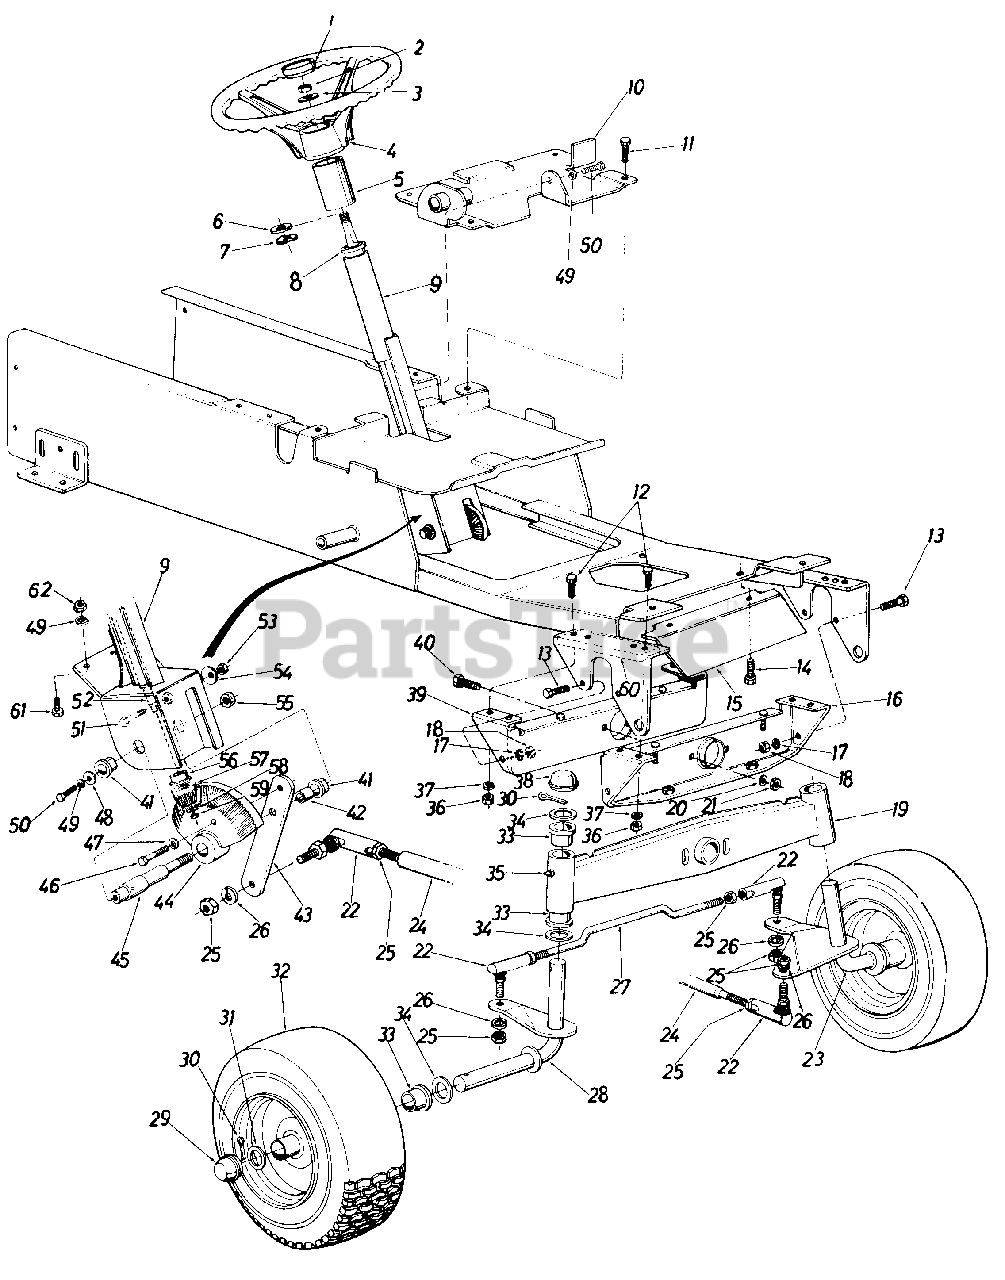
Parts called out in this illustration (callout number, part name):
1	Steering Wheel Cap
2	Hex Cent. L-Nut 5/16-18 Thd.
3	Bell-Wash.
4	Steering Wheel
5	Steering Tube-Outer
6	Double "D" Fl-Wash.
7	Wave Wash. .660 I.D. x .88 O.D.
8	Ball Brg. .63 I.D. x 1.38 O.D.
10	Dash Panel Base Plate Ass'y.
11	Hex Self-Tap Scr. 3/8-16 x .75" Lg.
12	Hex Scr. 3/8-16 x 1.50" Lg.
13	Hex Scr. 3/8-16 x 1.00" Lg.
14	Hex Wash. S.F. Tap Scr. 3/8-16 x 1.25" Lg.
15	Dust Shield
18	Hex Nut 3/8-16 Thd.
19	Pivot Bar Ass'y.
20	Bell-Wash. 3/8" Scr.
21	Hex Cent. L-Nut 3/8-16 Thd.
22	Drag Link End
23	Axle Ass'y.-L.H.
24	Drag Link
25	Hex Nut 1/2-20 Thd.
26	L-Wash. 1/2" Scr.
27	Tie Rod
28	Axle Ass'y.-R.H.
29	Dust Cover
30	Cotter Pin 3/16" Dia. x 1.50" Lg. *
31	Fl-Wash. 1.00" I.D. x 1.62"O.D.
33	Flange Brg. 1.00" I.D.
34	Fl-Wash. 1.00" I.D. x 1.62" O.D.
35	Grease Fitting
36	Hex Nut 3/8-16 Thd.
37	L-Wash. 3/8" Scr.
38	Dust Cover
40	Hex Scr. 3/8-16 x 2.50" Lg.
41	Flange Brg. w/Flats .753 I.D.
42	Steering Gear Shaft Spacer
43	Steering Arm
44	Bevel Gear
45	Steering Gear Shaft
46	Hex Scr. 3/8-16 x 1.50" Lg.
47	L-Wash. 3/8" Scr.
48	Fl-Wash. .406 I.D. x 1.25" O.D.
49	L-Wash. 3/8" Scr.*
50	Hex Scr. 3/8-16 x .75" Lg.
51	Nylon Hex Scr. 3/8-16 x 1.25" Lg.
52	Steering Shaft
53	Hex Jam Nut 3/8-16 Thd.
54	Bell-Wash. .400 I.D. x 1.13 O.D.
55	Hex Ins. L-Nut 1/2-20 Thd.
56	Hex Flange Brg. .630 I.D.
57	Pinion Gear
58	Fl-Wash. 3/8" Dia.
59	Hex Cent. L-Nut 5/16-24 Thd.
62	Hex Nut 3/8-24 Thd.
